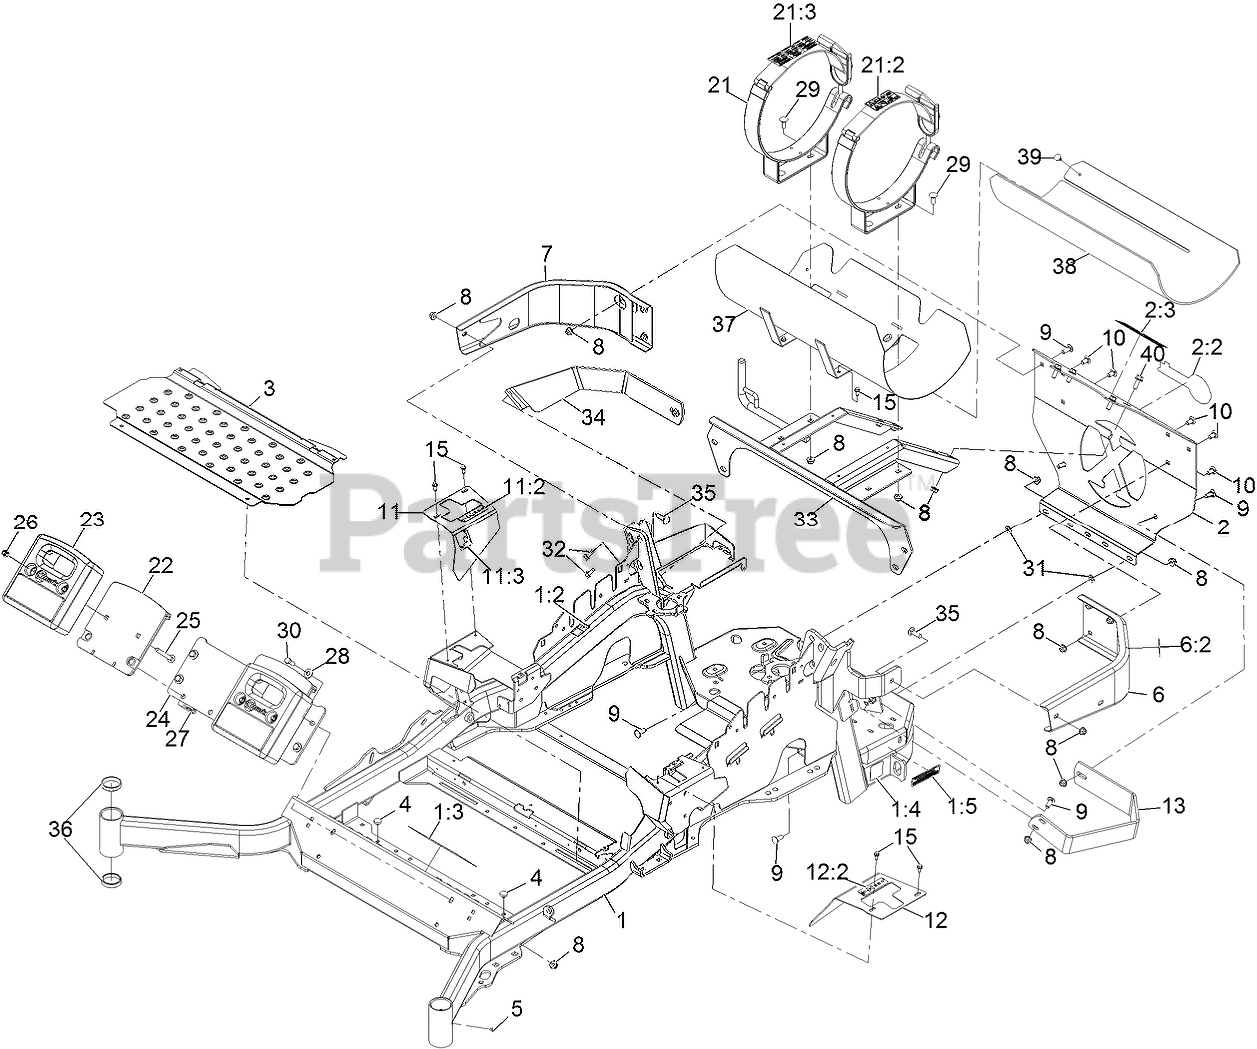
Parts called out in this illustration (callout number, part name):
1	MAINFRAME ASM
1:2	DECAL-WARNING
1:3	DECAL-DANGER
1:4	DECAL-HAZARD, PINCHED FINGER
1:5	DECAL-ARRESTOR, SPARK
2	REAR GUARD-LP W/DECALS
2:2	DECAL, EXMARK LOGO
2:3	Decal-LPG Fuel Tank Replacement
6	LH BUMPER ASM
6:2	DECAL-WARNING
7	BUMPER-RH
8	NUT-HF, NI
9	SCREW-CARR
10	SCREW-CARR
11	RH MOTION CONTROL COVER ASM
11:2	DECAL-CONTROL, MOTION
11:3	DECAL-PARK BRAKE, CE
12	LH MOTION CONTROL COVER ASM
12:2	DECAL-CONTROL, MOTION
13	GUARD-MUFFLER
15	SCREW-HWH
21	TANK BRACKET ASM (SET)
21:2	Decal-LPG Warning
21:3	Decal-LPG Tank Spec
22	WLD,WEIGHT MOUNT
23	WEIGHT,CAST 36LB
24	PLATE,WEIGHT ASM MOUNT
25	SCREW-CARR
26	NUT-LOCK, NI
27	PIN-HAIR
28	WASHER-BELLEVILLE
29	BOLT-CARR
30	SCREW-HH
31	NUT-PUSH
32	Screw-HWH 5/16-18 X 3/4 Tf
33	SUPPORT-TANK
34	STRAP-GUARD
35	BOLT-CARR
36	CUP-BEARING
37	WLD,LP TANK HEAT SHIELD
38	THERMAL BARRIER-43# LP TANK
39	PLUG-PLASTIC
40	SCREW-HHF 3/8-16 X 1
